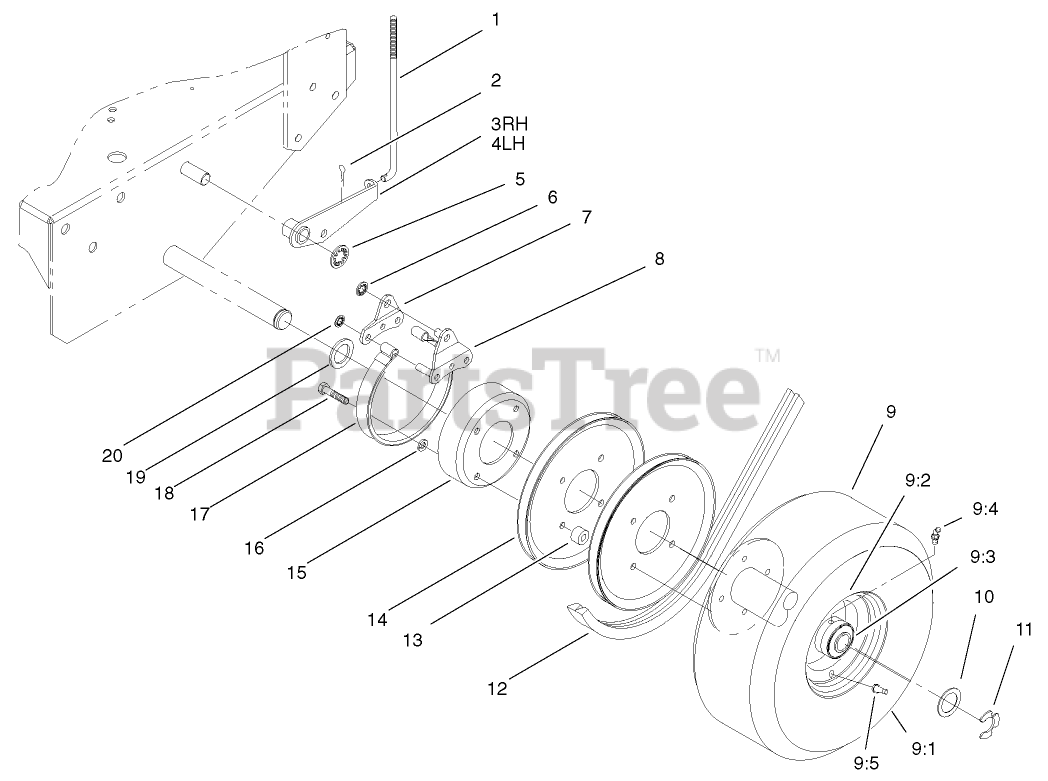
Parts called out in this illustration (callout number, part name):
1	ROD-BRAKE
2	PIN-COTTER
3	ARM-BRAKE, RH
4	ARM-BRAKE, LH
5	RING-RETAINING
6	RING-RETAINING, EXTERNAL
7	PLATE-LINK, BRAKE
8	LINK-BRAKE
9	WHEEL AND TIRE ASM
9:1	TIRE-FRONT
9:2	WHEEL ASM
9:3	BEARING-BALL
9:4	FITTING-GREASE
9:5	STEM-VALVE
10	WASHER-THRUST
11	RING-RETAINING
12	V-BELT
13	SPACER-PULLEY
14	PULLEY-WHEEL
15	DRUM-BRAKE
16	WASHER-LOCK
17	BAND-BRAKE
18	SCREW-HH
19	WASHER-WHEEL
20	RING-RETAINING
